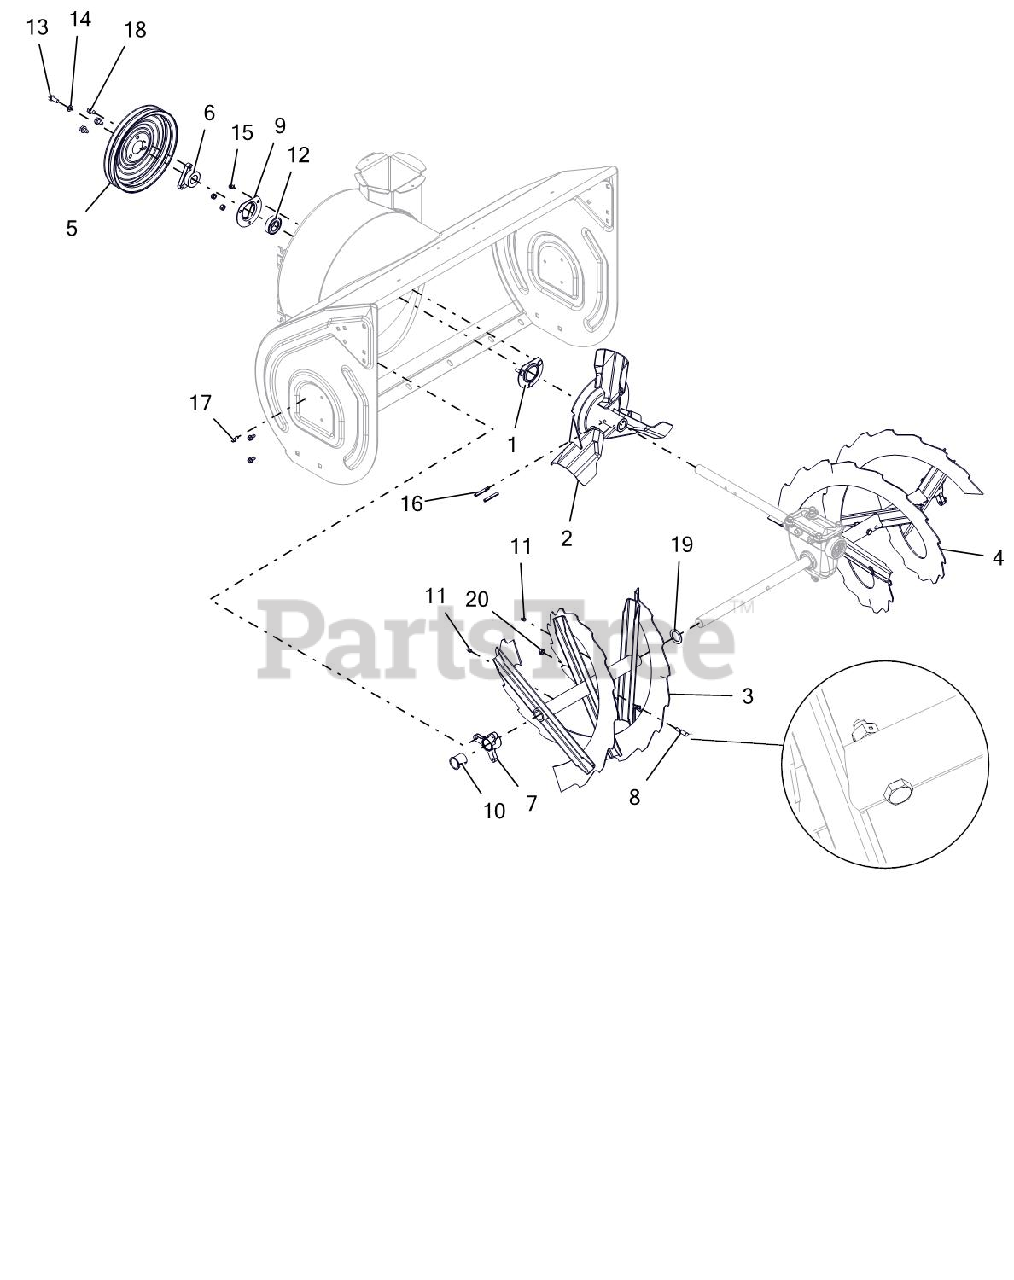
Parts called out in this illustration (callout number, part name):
1	BEARING FLANGE
2	IMPELLER, 3 BLADE-14"
3	RAKE, RH-32"(1 ID X 15.75 OD)
4	RAKE, LH-32"(1 ID X 15.75 OD)
5	PULLEY, SPIN FORM DUAL GROOVE
6	PULLEY HUB, D-BORE .87 PRO
7	BUSHING, RAKE SHAFT 1"
8	SHEAR BOLT SERVICE ASSEMBLY
9	BEARING FLANGE
10	BSHG-FLG SPLIT NYLINER 1.0" HP
11	ZERK,FITTING .25X.125 DRIVE IN
12	BRG-BALL .876X1.75X.50 RSTFP
13	BLT-HEX .31-24X.75 YWZC GR5
14	WSHR-LK .312X.097 HVY YWZC
15	@NUT-LK-CTR .25-20 YWZC
16	PIN-ROLL .250X1.75
17	SCR-TAP .25-20X.50 HWH TR YWZ
18	@SCR-TAP .31-18X.50 HWH TR YWZ
19	WSHR-FL-STL 1.010X1.505X.062YZ
20	@NUT-LK-CTR .31-18 YWZC
